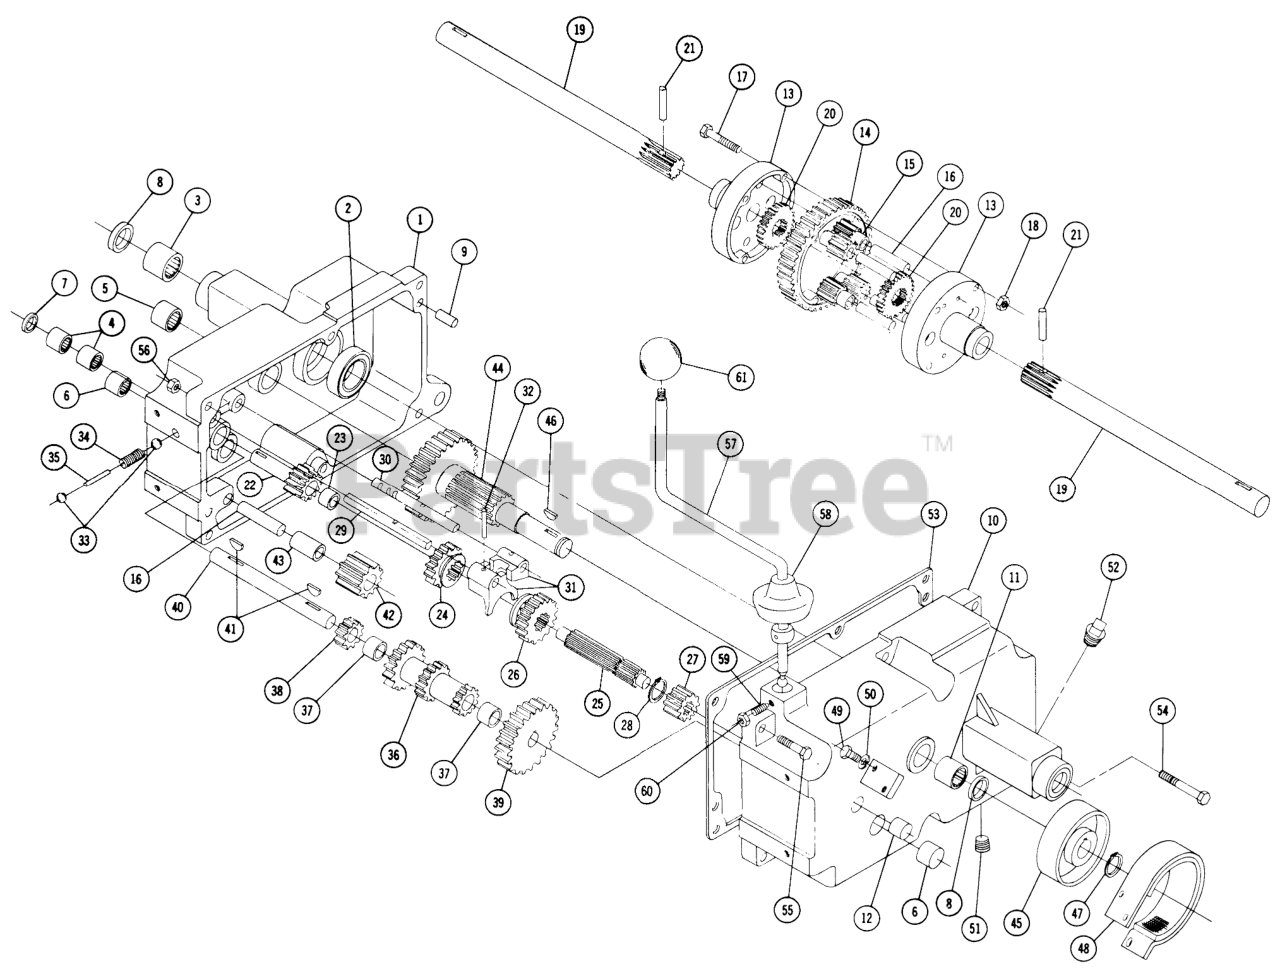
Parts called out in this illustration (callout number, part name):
3	BEARING-NEEDLE
5	BEARING-NEEDLE
6	BEARING-NEEDLE
9	OWNERS MANUAL
13	DIFFERENTIAL CASE
14	SVC BULLT 394
16	PIN-DIFFERENTIAL
20	AXLE GEAR
23	BEARING-NEEDLE
27	GEAR
29	RAIL-SHIFT
30	RAIL-REAR SHIFT
31	FORK-SHIFT
32	PIN-ROLL
33	BALL-DETENT
35	PIN-SHIFT
37	BUSHING-BRONZE
39	GEAR-CLUSTER SHAFT
41	Key
42	GEAR/BUSHING ASM-REVERSE IDLER
43	BUSHING
46	KEY-WOODRUFF
48	BRAKE BAND & LINER A
49	Bolt-1/4-20 x 5/8
50	Lockwasher
53	GASKET-TRANSMISSION
54	Bolt Hex 3/8-16 x 1
55	Bolt, 3/8 16 x 2
58	COVER-DUST
59	SETSCREW
60	Nut-Nylok
